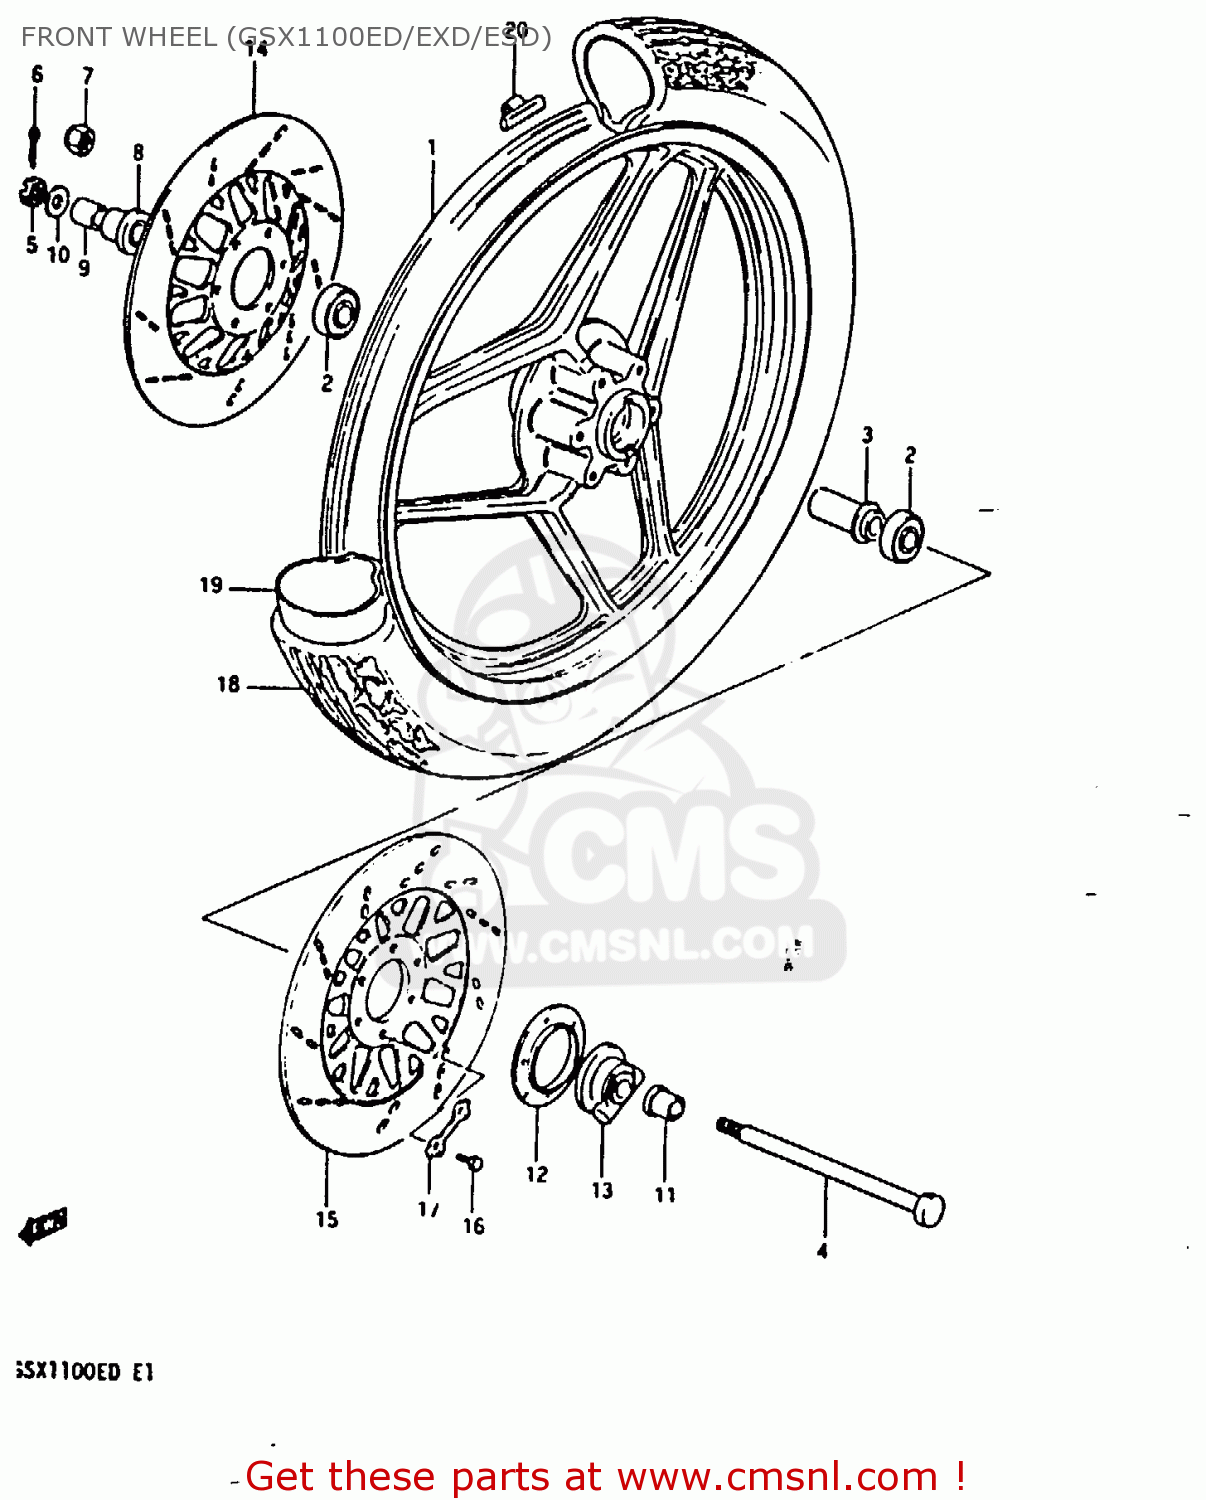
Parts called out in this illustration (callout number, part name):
1	CASTING WHEEL,FRONT 1.85
2	BEARING
3	SPACER,FR HUB BEARING
4	AXLE,FR
5	NUT 12MM
6	COTTER PIN
8	SPACER,FR AXLE,R
9	SPACER,FR AXLE,R
10	WASHER
11	SPACER,FR AXLE,L
12	DUST SEAL,SPEEDOMETER GEAR BOX
13	BOX ASSEMBLY,SPEEDOMETER GEAR
14	DISC,FR BRAKE,R
15	DISC,FR BRAKE,L
16	BOLT(8X25)
17	WASHER
18	TIRE, FRONT (3.50V19)
19	TUBE,INNER
20	BALANCER,WHEEL
